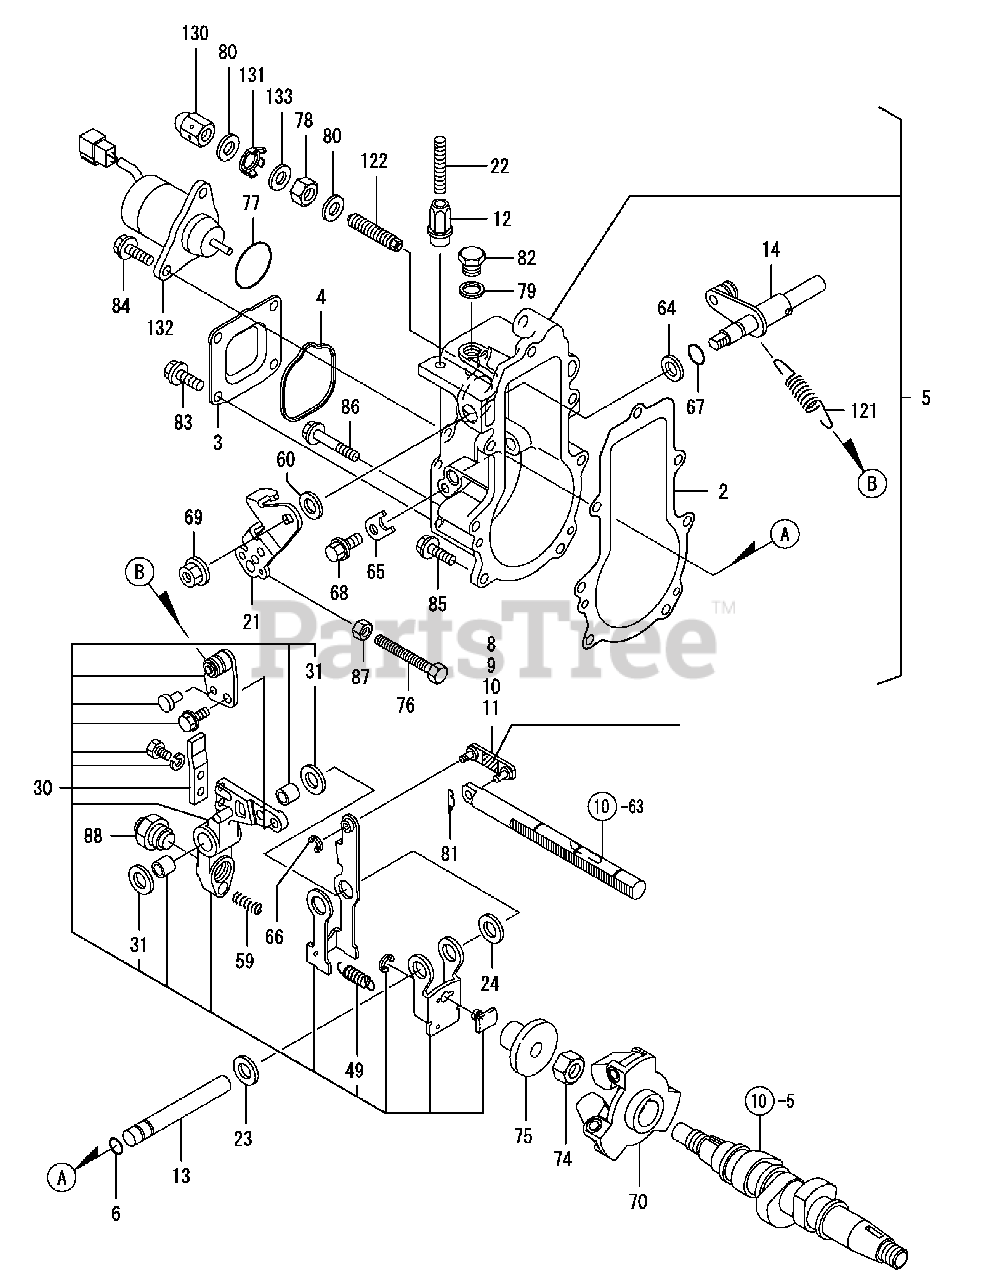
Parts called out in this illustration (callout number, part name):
3	Case, Governor
5	Case Assembly, Governor
13	Shaft, Gov. Lever
14	Shaft Assembly, Control
21	Lever, Control
22	Bolt, Revol. Limit
24	Spacer Assembly
30	Lever Assembly, Governor
59	Spring, Fuel Control
65	Retainer, Shaft
68	Bolt, 6 x 10 Plated
70	Weight Assembly
74	Nut, Governor Weight
76	Bolt, Idle Limit
83	Bolt, 6 x 10 Plated
84	Bolt, M 6 x 14 Plated
85	Bolt, M 6 x 20 Plated
86	Bolt, M 6 x 45 Plated
88	Angleich Assembly
121	Spring, Governor
122	Limiter Assembly, Fuel
132	Solenoid, Stop
